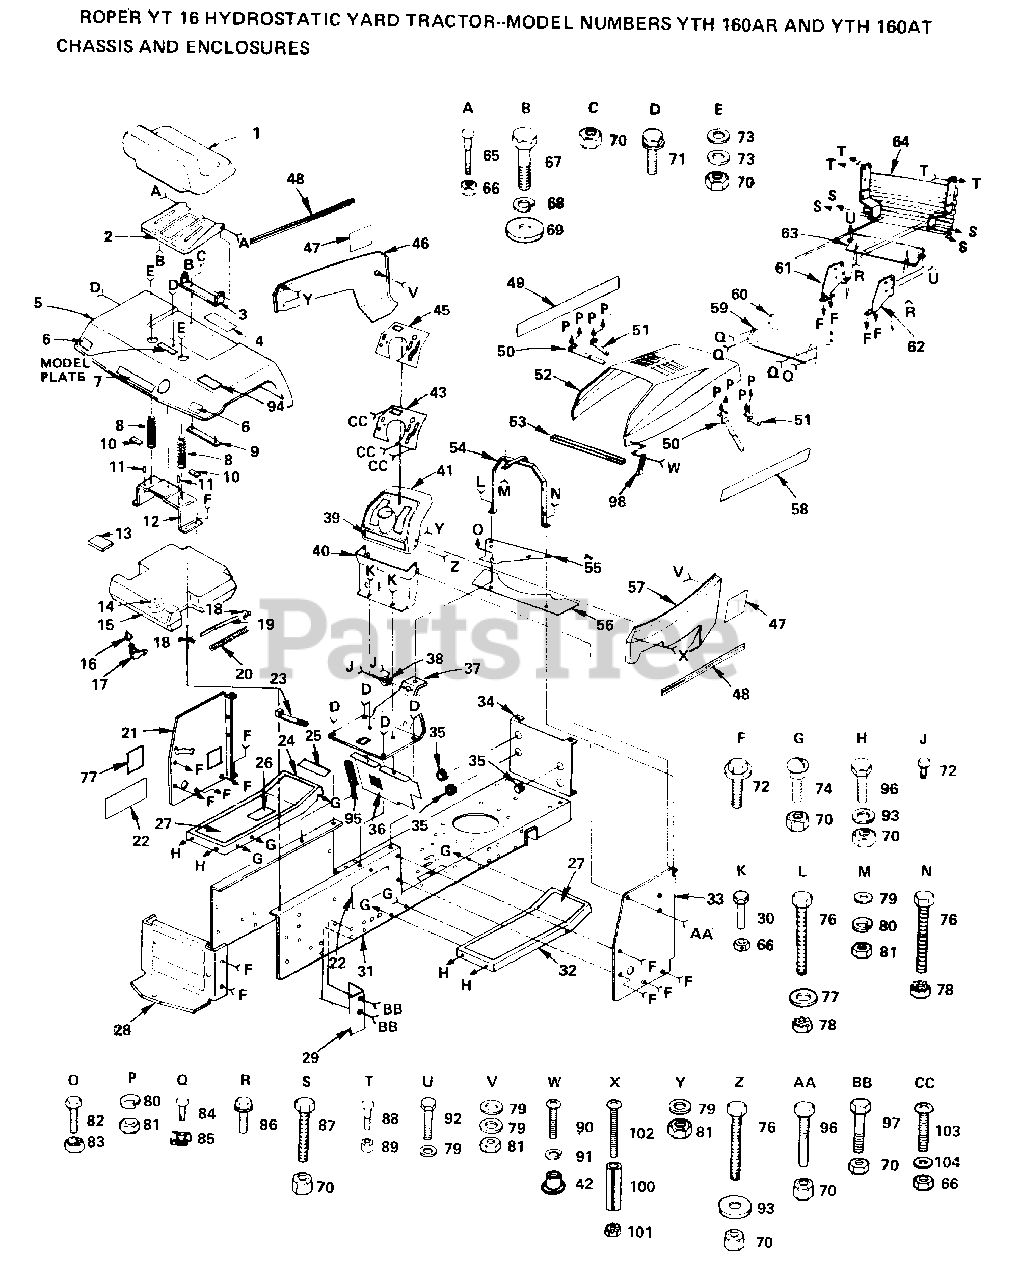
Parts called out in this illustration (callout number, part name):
6	REFLECTOR-TAIL YT
10	"CLAMP, SPRING LT"
11	NUT-PUSH YT
13	PAD-SPACER LT
16	BUSHING OUTLET T
17	FUEL TANK STEM GT
20	COVER - CABLE
21	PANEL DASH HYT
25	DECAL T
27	PAD FOOTREST T
35	SNAP BUSHING T
40	LOWER DASH
42	WELDNUT
44	WASHER
47	DECAL-SIDE PANEL
53	FOAM-STRIP LT
60	LENS LT
61	SUPPORT-GRILL LT
67	BOLT
69	WASHER
71	SCREW LT
72	SCREW
73	WASHER
74	BOLT
78	NUT
79	WASHER PM
82	BOLT
85	"""J"" FASTENER LT"
86	SCREW
87	BOLT
88	BOLT T
90	SCREW
91	LOCKWASHER
92	SCREW HEX CRT
93	WASHER
94	DECAL-CAUTION
95	FOAM STRIP HYT
100	SPACER LT
101	WASHER
102	SCREW
103	SCREW
104	WASHER
